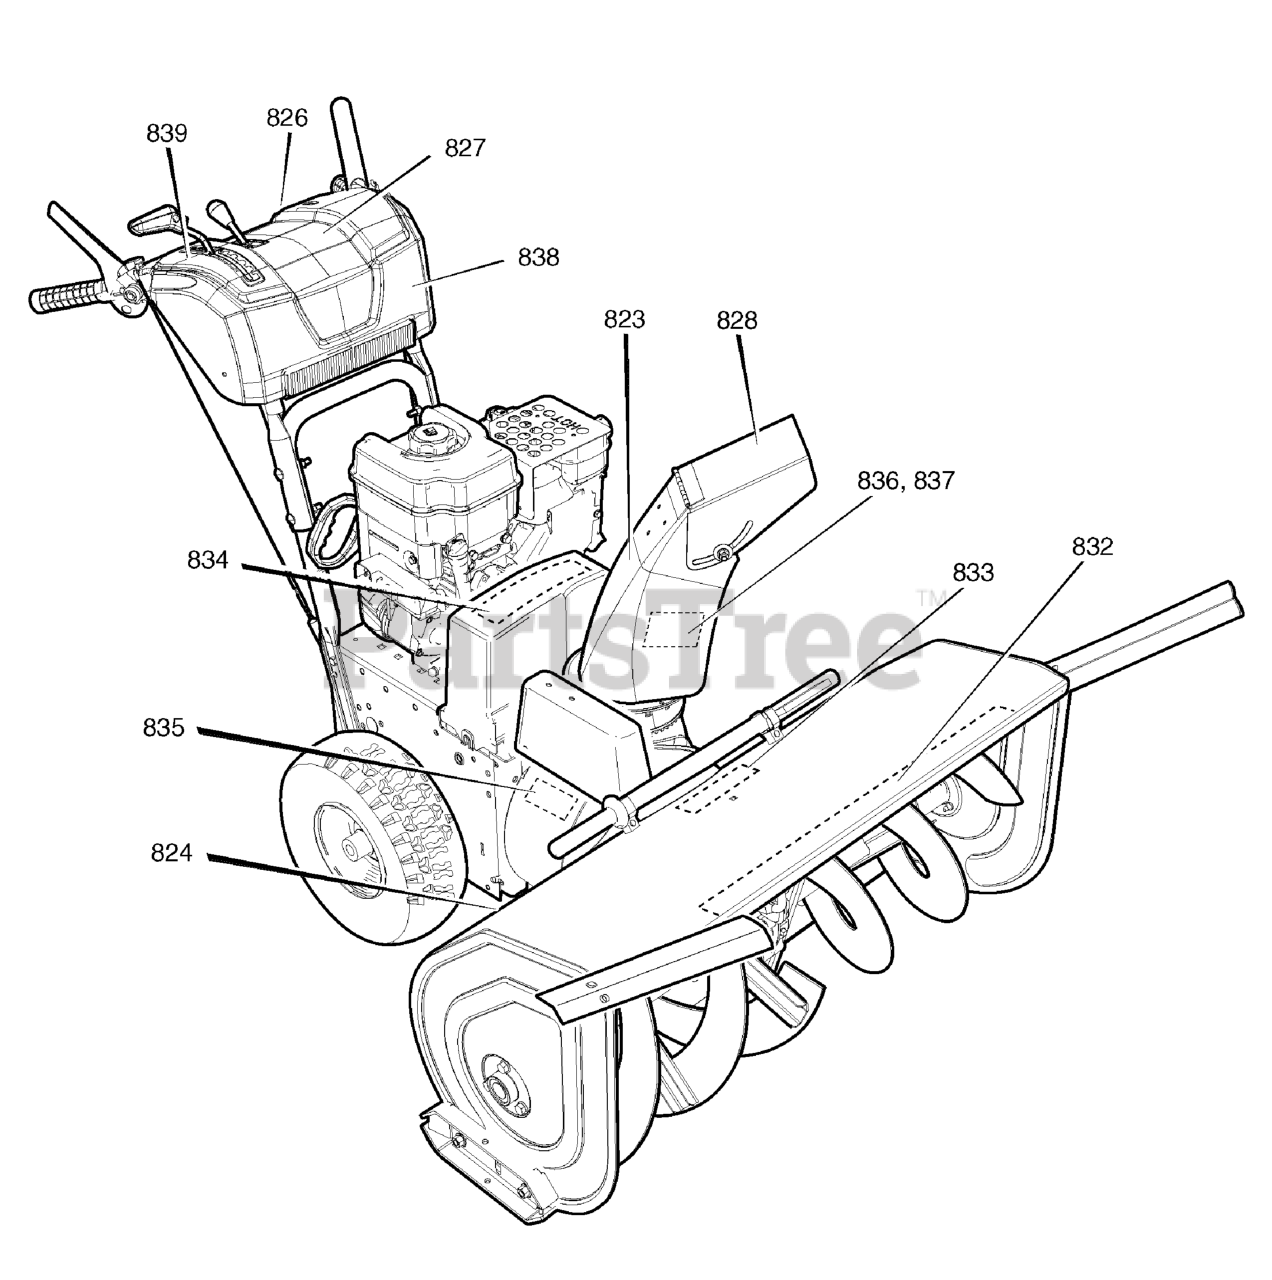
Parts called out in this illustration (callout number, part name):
823	DECAL, DANGER CHUTE HAND
824	DECAL, DANGER FOOT
826	DECAL, LUBRICATION POINT
827	DECAL, Dash
828	DECAL, THROWN OBJECTS
832	DECAL, CRAFTSMAN AUGER 1650/31
833	DECAL, CLEAN & CLEAR BRUSH
834	DECAL, TOOLBOX INFORMATION
835	DECAL, PINCH POINT ELECTRIC
836	DECAL, POWER 2 STEER, ENGLISH
837	DECAL, POWER 2 STEER, FRENCH
838	DECAL, CRAFTSMAN
839	DECAL, Shift, R1, R2, 1-6
